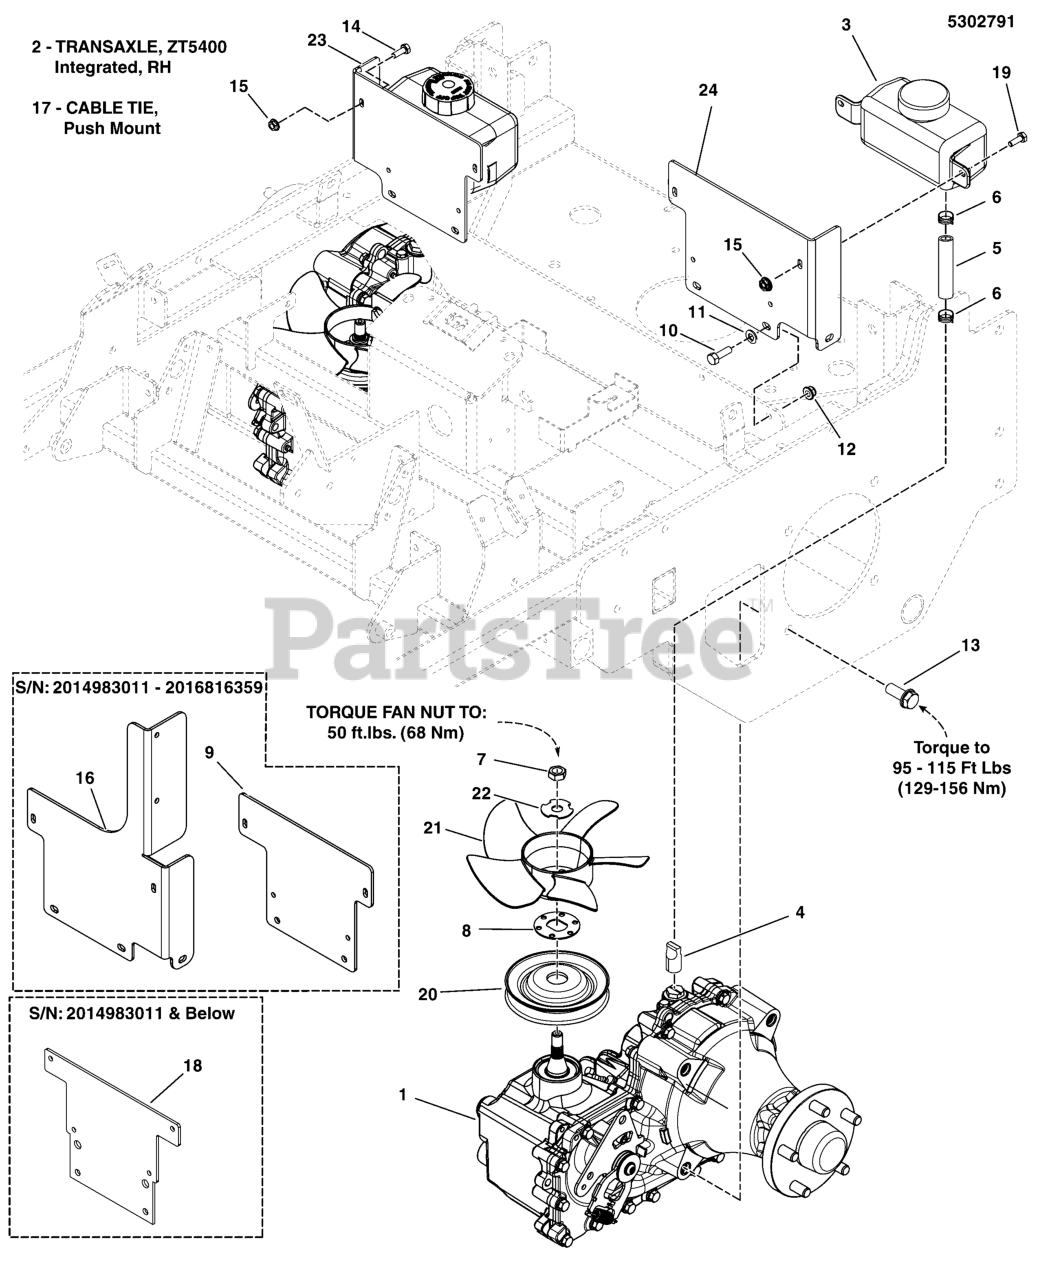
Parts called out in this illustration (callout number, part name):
1	TRANSAXLE, ZT5400, LH, 1015-1024L
3	HYDRO TANK, HYDRO-GEAR 71938, 1 LITER
4	FITTING, BREATHER, ZT5400
5	HOSE, OFFSET FORMED
6	CLAMP, #10 HOSE, STAINLESS
7	NUT, ZT5400
8	SPACER, ANTI-ROTATE, ZT5400
9	PLATE, HYDRO RES TANK - BLK
10	BOLT, 5/16-18 X 3/4 GD5
11	WASHER, 5/16" SAE
12	NUT, 5/16-18 HEX NYLOCK FLANGE
13	BOLT,HEX FLG,SER,GD8 1/2-13X1-1/4W/PATCH
14	BOLT, 1/4-20 X 1" GD5 CZ
15	NUT, 1/4-20 HEX NYLOCK FLANGE
16	BRACKET, HYDRO TANK/CARBON CANISTER - RED
18	PLATE, HYDRO TANK RES - RED
19	BOLT, 1/4-20 X 3/4
20	PULLEY, ZT5400
21	FAN, ZT5400
22	WASHER, ZT5400, SLOTTED
23	BRKT, HYD TNK/CARB CAN, S200XT RH - BLK
24	BRACKET, HYD TANK, S200XT, LH - BLK
